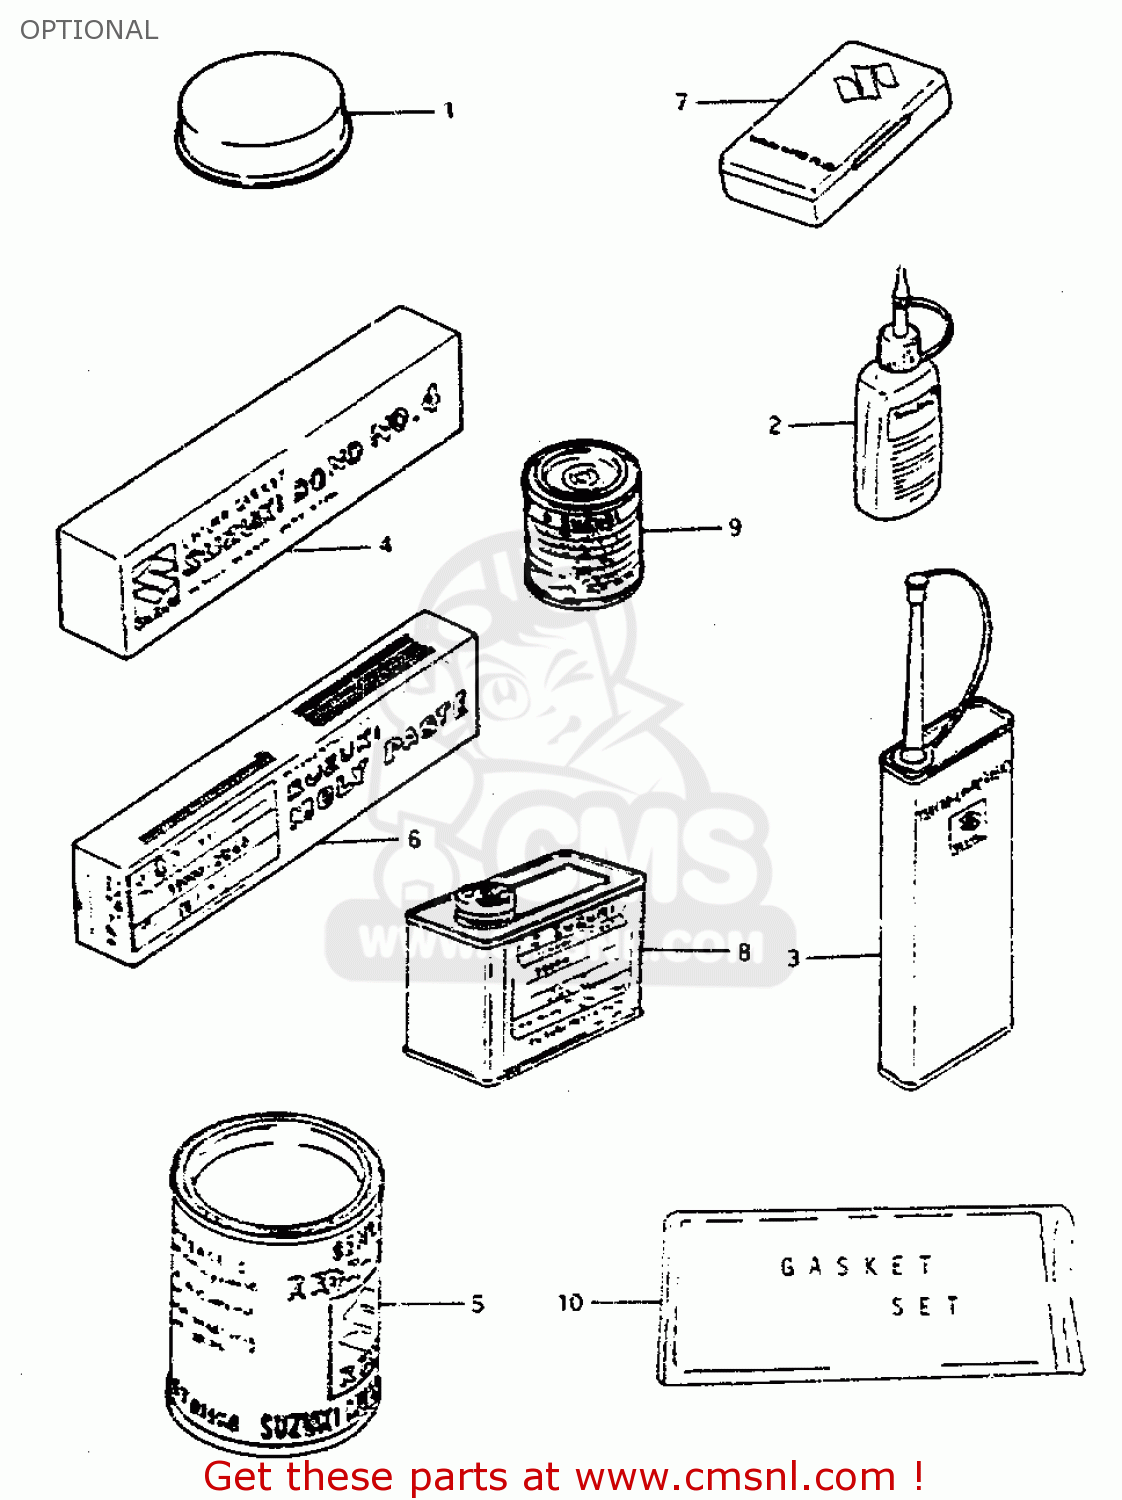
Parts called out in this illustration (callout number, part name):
1	GREASE,PBC FOR BRK PAD 20G
2	THREAD LOCK SUPER (1332B)
3	THREAD LOCK NO.1401 CLEAR 200G
4	BOND 1104
5	GREASE(C)EP2 LITHIUM 150G
6	SUZUKI MOLY PASTE
7	TUBE REPARING TOOL
8	PAINT (BLACK)
9	PAINT,BLACK
10	GASKET SET
